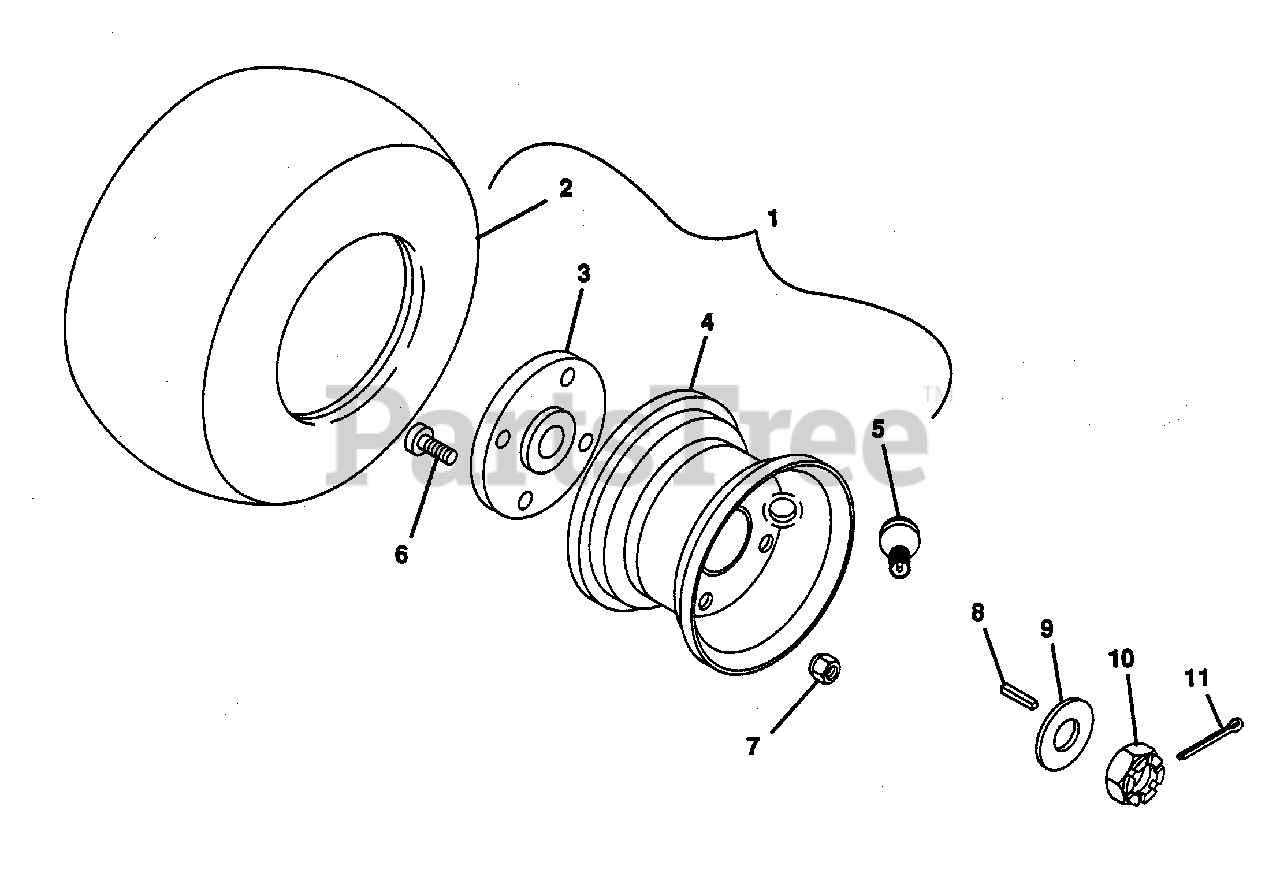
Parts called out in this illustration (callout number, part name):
1	Wheel Asm., 16x6.50-8
2	Tire, 16x6.50-8
3	Assembly, Hub
4	Assembly, Rim
5	Assembly, Valve Stem
6	Bolt, 1/2-20x 1.25 Pan Head
7	Nut, Rim
8	Key, Square .187x.750
9	Washer, Flat .813x1.37x.100
10	Nut, Hex 3/4-28 Slotted
11	Pin, Cotter .094x1.25
